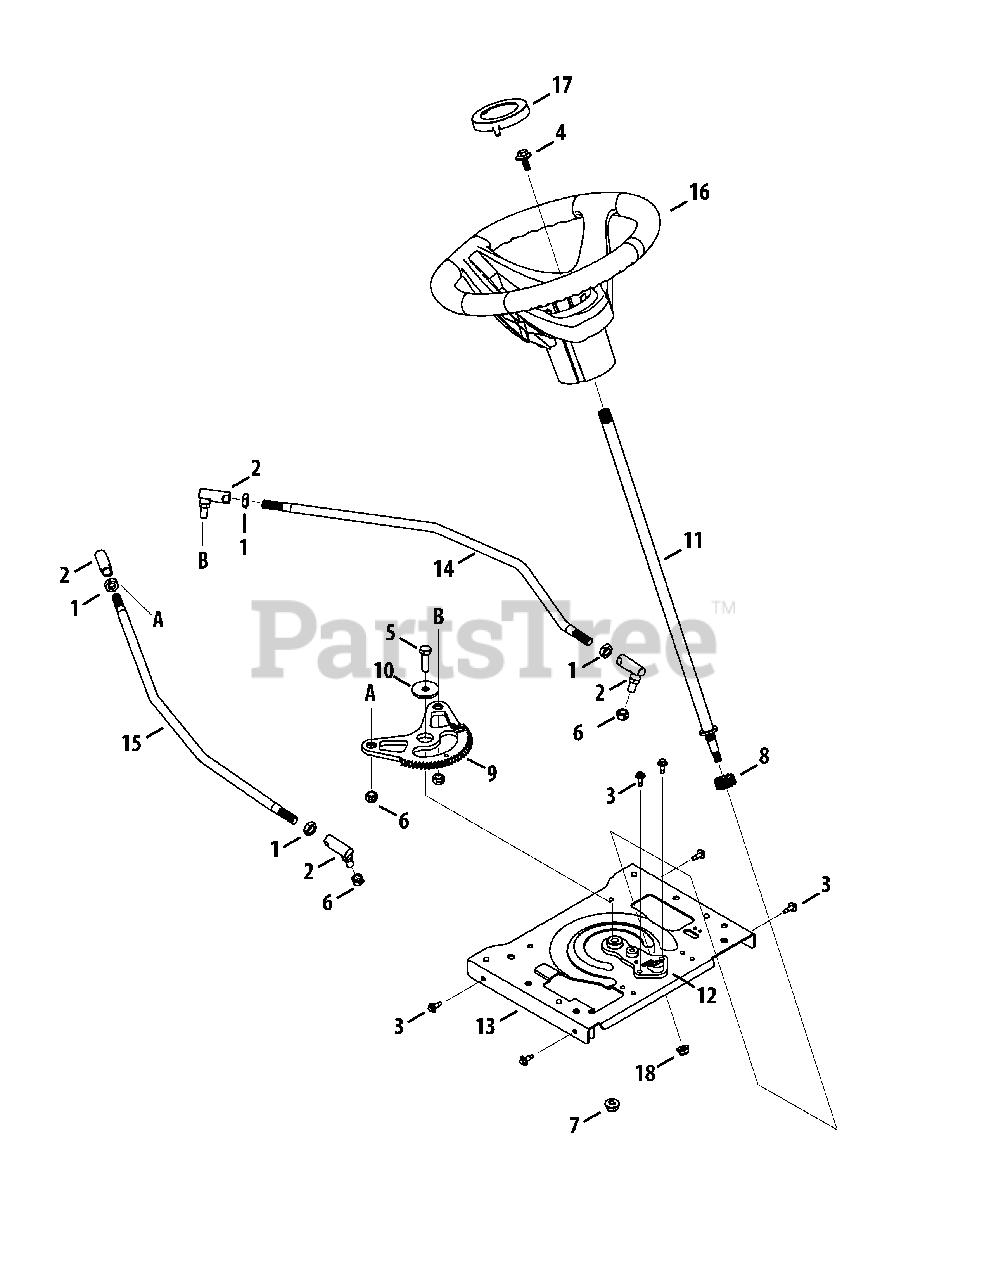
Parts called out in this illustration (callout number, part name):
1	Jam Nut, 7/16-20
2	Ball Joint, 7/16-20, Lock
3	Screw, M6-1 x .625
4	Screw, 5/16-24 x .850
5	Hex Cap Screw, 3/8-16 x 1.25
6	Nut, Hex Lock, 3/8-24, Grb
7	Nut, Flange Lock, 3/8-16, Grf,
8	Pinion Gear, 13T
9	Steering Gear
10	Flat Washer, .390 x 2.490 x .119
11	Shaft, Steering, .625 OD x 20
12	Steering Support
14	Steering Rod, LH
15	Steering Rod, RH
16	Steering Wheel
17	Cap, Steering Wheel
18	Nut, Flange Lock, 5/16-18, Grf
